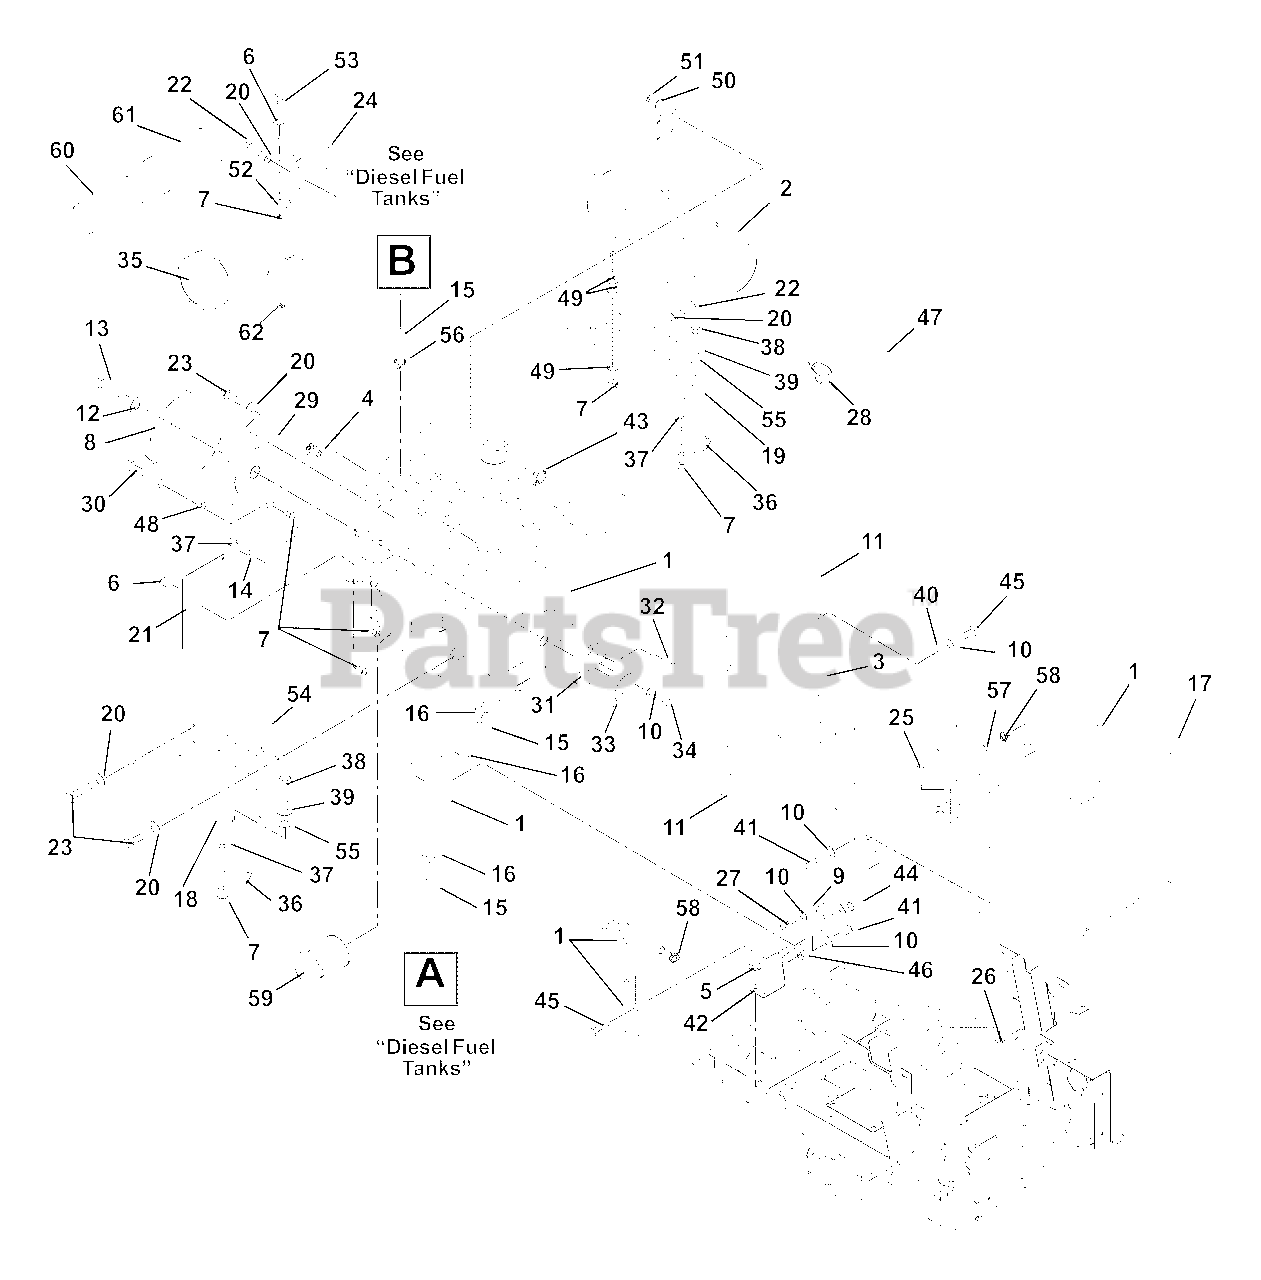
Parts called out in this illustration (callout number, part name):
1	Engine, 27HP Diesel (Daihatsu) (075, 318)
1	Engine, 31HP Diesel (Daihatsu) (076, 319)
2	Muffler (075, 318)
2	Muffler (076, 319)
3	Weldment, Radiator Shroud
4	Sender, Temperature
5	Screw, Tapping .38-16 x .75 Hex Washer Head
6	Bolt, Hex .31-18 x .75 Grade 5
7	Nut, Locking Top Flange .31-18
8	Electric Clutch
9	Washer, Flat Steel .281 x .62 x .065
10	Washer, Locking .25 x .062 Regular
11	Seal, Trim-LOK Bulk .06 Bubble
12	Washer, Locking .44 x .109
13	Bolt, Hex .44-20 x 2.50 Grade 5
14	Stabilizer, Clutch
15	Gas Line, Bulk .31" ID
16	Hose, Clamp
17	Screen, Radiator
18	Mount, Engine Right Hand
19	Mount, Engine Left Hand
20	Washer, Lock .31 x .078 Regular
21	Guard, Flywheel
22	Bolt, Hex M8-1.25 x 20
23	Bolt, Hex M8 x 1.25 x 25 Grade 8
24	Bracket, Air Cleaner
25	Bolt, Hex .38-16 x 1.00 Grade 5
26	Nut, Locking Top Flange .38-16
27	Bolt, Hex M6-1.00 x 45
28	Clamp, 2.50" Dia. Hose
29	Weldment, Stub Shaft (076, 319)
30	Bolt, Hex .31-18 x 1.50 Grade 5
31	Adapter, Sheave
32	Bolt,
33	Sheave, Poly-V 1.0 x 3.25
34	Bolt, Hex .25-20 x .75 Grade 5
35	Assembly, Air Cleaner
36	Mount, Engine
37	Bolt, Hex .31-18 x 1.00 Grade 5
38	Bolt, Hex .50-20 x 1.00 Grade 5
39	Washer, Locking .50 x .125 Regular
40	Bracket, Radiator Mounting
41	Bolt, Hex M6-1 x 16
42	Bracket, Overflow Mounting
43	Clamp, Hose 1.50 x .81 x 1.42
44	Spacer .328 x .76 x 1.01
45	Bolt, Hex .25-20 x .75 Grade 5
46	Nut, Locking Top Flange .25-20
47	Hose, Air Cleaner (075, 318)
47	Hose, Air Cleaner (076, 319)
48	Nut, Hex .31-18
49	Washer, Flat Steel .38 x .875 x .083
50	Washer, Locking .31 x .078 Regular
51	Nut, Hex M8-1.25
52	Bracket, Air Cleaner Mount
53	Washer, Flat Steel .38 x .875 x .083
54	Spacer, Engine Mounting
55	Washer, Flat Steel .531 x 1.06 x .095
56	Hose Clamp
57	Gas Line, Bulk .25 I.D.
58	Clamp, Hose Wire .49/.51 x .116
59	Oil Filter
60	Element, Inner Safety
61	Element, Outer Primary
62	Plug, Pipe .125-27
NS	Kit, Break Pole Module Replacement
